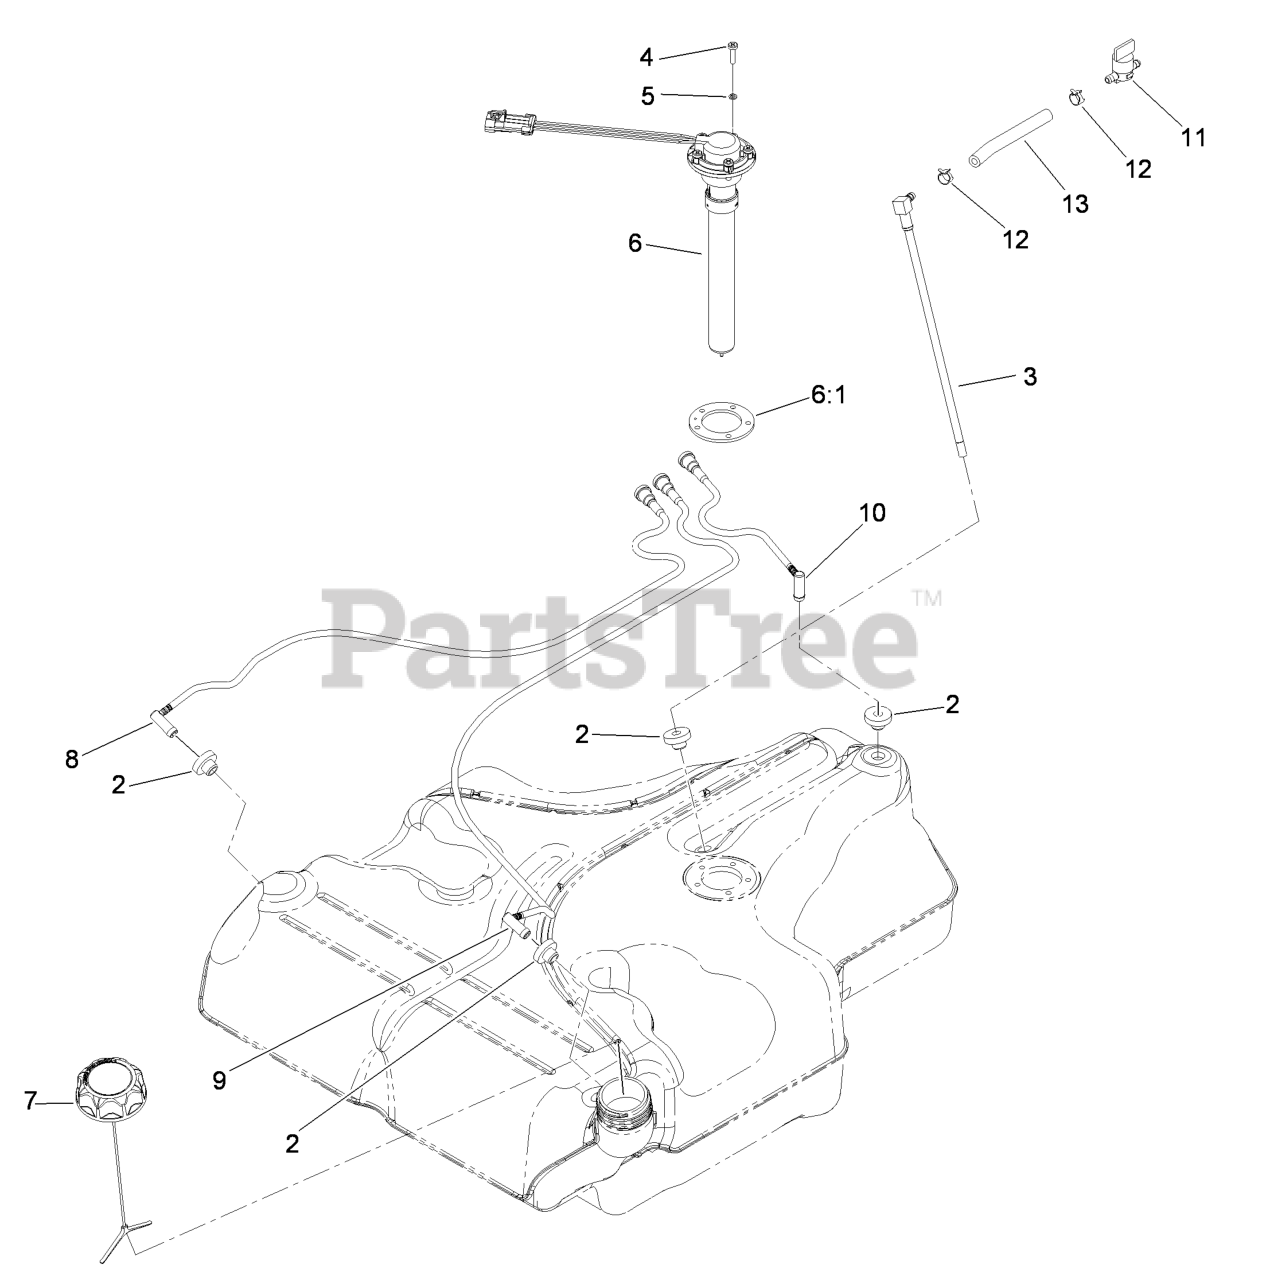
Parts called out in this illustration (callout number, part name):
2	BUSHING
3	FUEL LINE KIT (WITH GROMMET)
4	SCREW-PAN
5	WASHER-LOCK
6:1	GASKET-SENDER, FUEL
8	RH VENT LINE KIT (WITH GROMMET)
9	LH VENT LINE KIT (WITH GROMMET)
10	REAR VENT LINE KIT (WITH GROMMET)
11	VALVE-FUEL
12	CLAMP-HOSE
13	HOSE-FUEL
